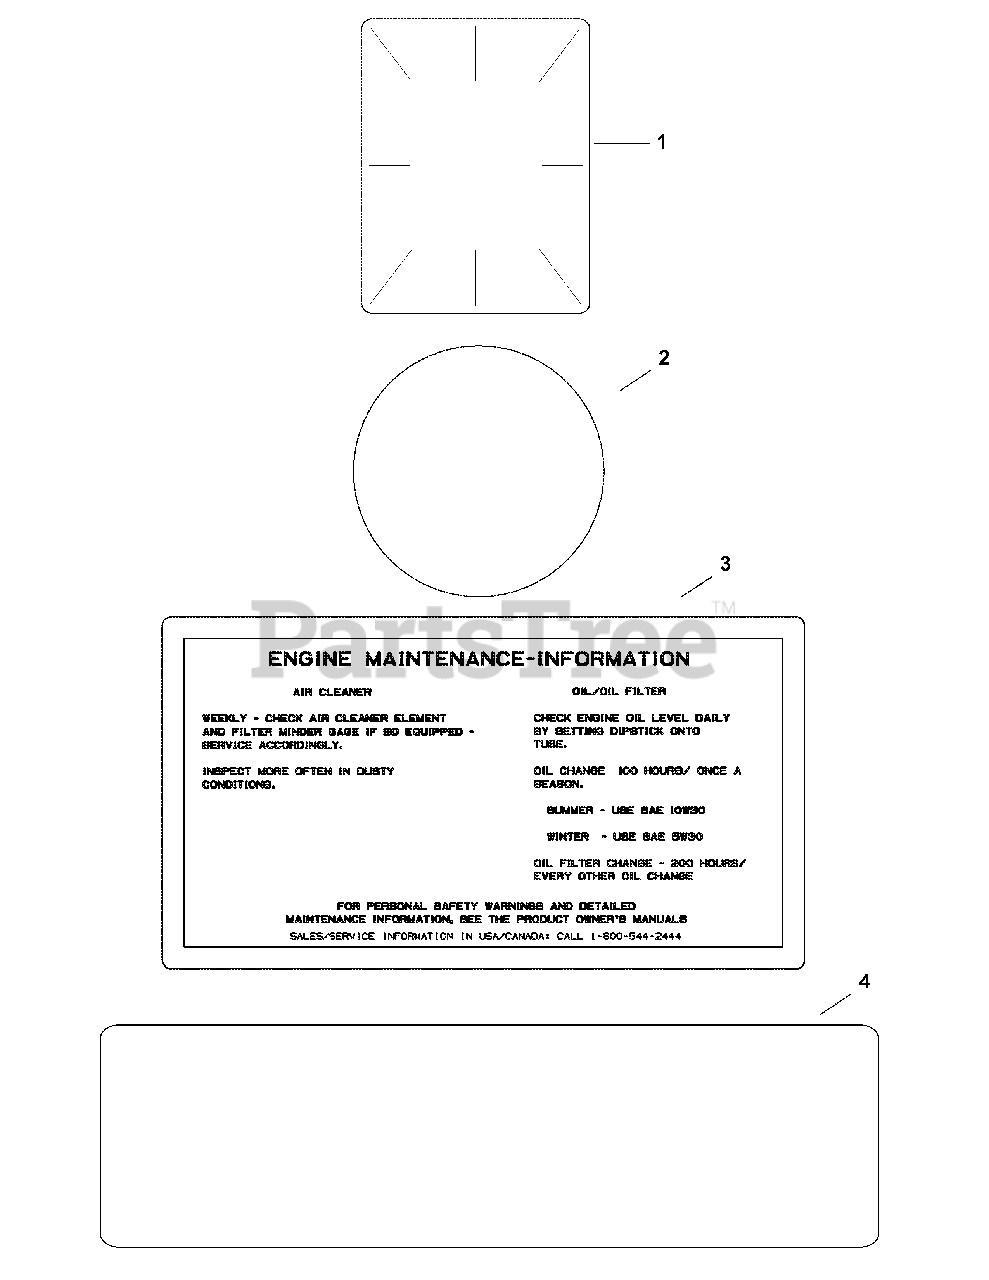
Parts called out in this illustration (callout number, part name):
1	Decal, Clear Laminate
2	Decal, Grass Screen
3	Decal, Air Cleaner
4	Decal, Command 23HP
